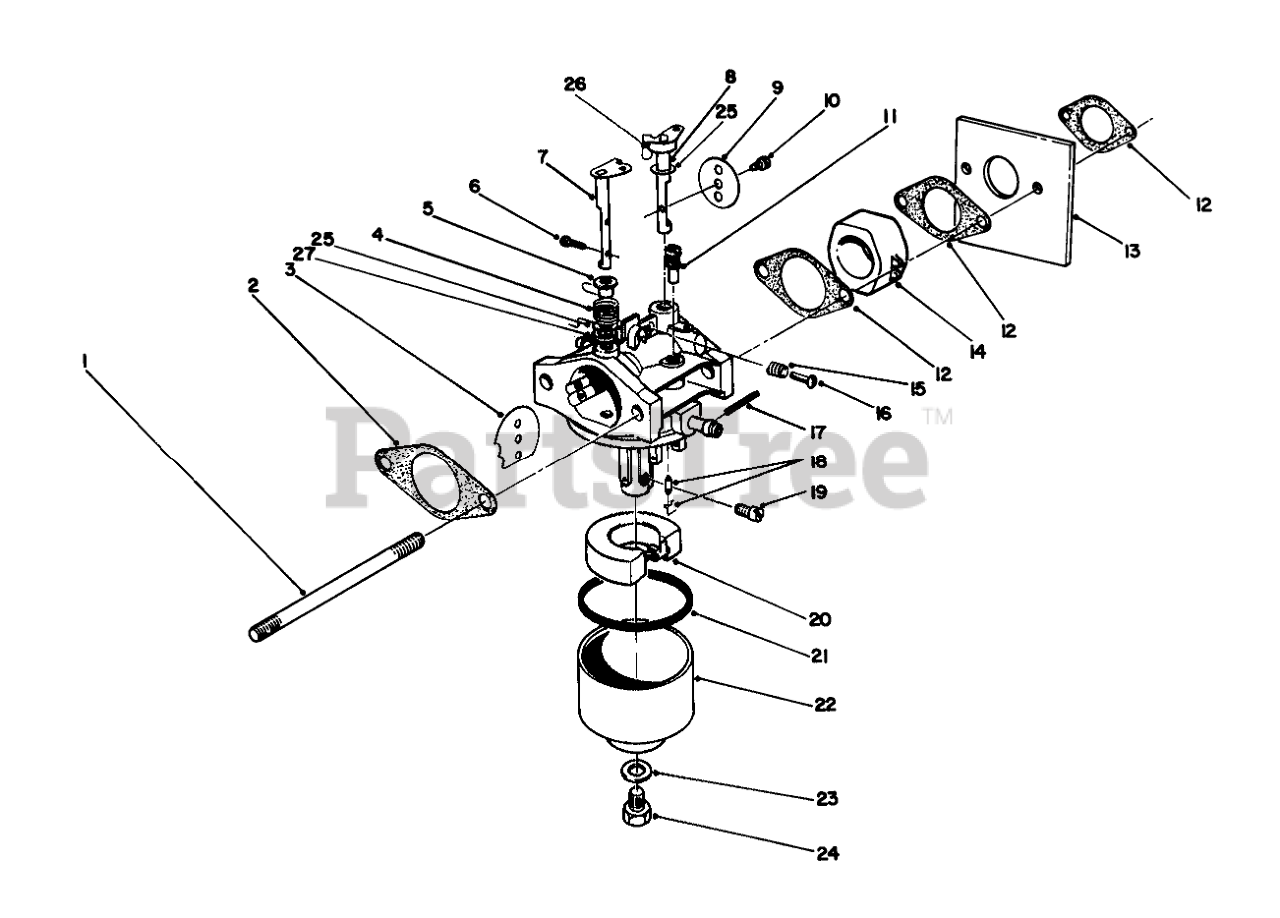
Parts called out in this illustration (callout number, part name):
1	STUD-CARBURETOR
2	GASKET-AIR CLEANER
3	PLATE
4	SPRING
5	BUSHING
6	SCREW
7	SHAFT-CHOKE
8	SHAFT
9	PLATE
10	Screw-Throttle
11	PILOT JET
12	GASKET-CARB
13	SHIELD-CARBURETOR
14	INSULATOR
15	SPRING-PILOT SCREW
16	SCREW
17	PIN-HINGE
18	NEEDLE
19	JET-MAIN
20	FLOAT
21	GASKET
22	BOWL - FLOAT
23	GASKET
24	SCREW
27	PACKING
